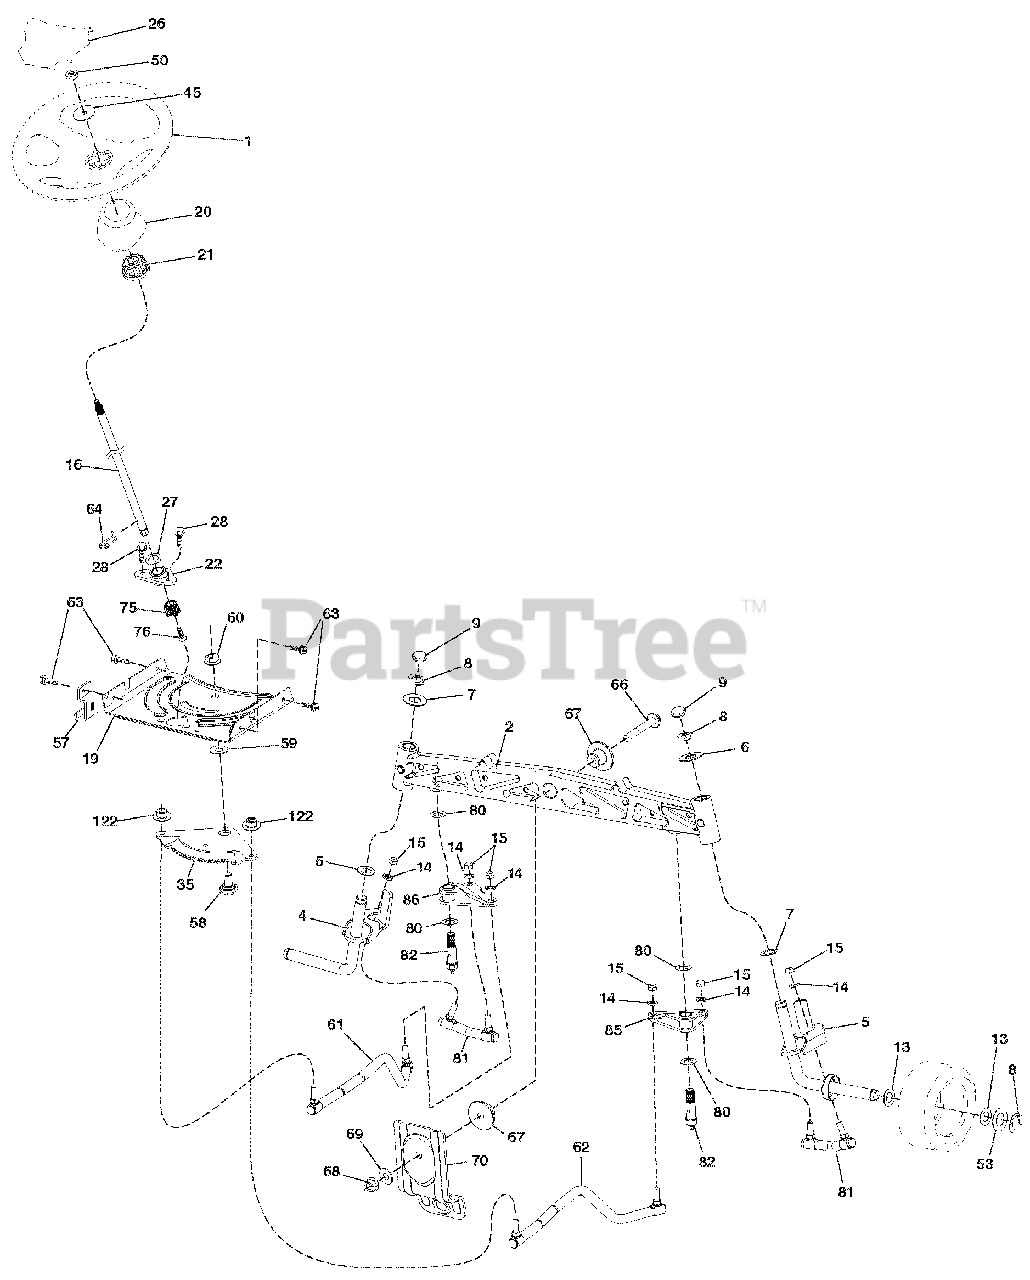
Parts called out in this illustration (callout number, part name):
1	WHEEL STEERING
4	SPINDLE LH
5	SPINDLE RH
6	WAHSER THRUST .75 X 1.230
7	WASHER.25/32 X 1-5/8 X 16GA.
8	RING.KLIP.#T5304-75
9	CAP.SPINDLE.FR.TOP.BLK.
13	WASHER.25/32 X 1 1/4 X 16 GA.
14	Washer, Lock 3/8
15	NUT.CROWNLOCK.3/8-24
16	SHAFT STEER
19	PLATE.STEER.DDL.NLT/NGT
20	BOOT.STEERING
21	ADAPTER.STEER
22	BEARING
26	CAP WHEEL STEERING HRS/SRS BLK
27	WASHER 21/32 X 1 X 1 GA.
28	SCREW.HEXWSH THDR3/8-16X3/4.BL
35	GEAR SECTOR
50	Nut, Hex, Flangelock 3/8-16
53	WASHER.HARDEN..793 X 1.637X060
57	BRACKET.UPSTOP.GT/LT.TEX
58	BOLT.SHOULDER.SECTOR.PIVOT.CFM
59	WASHER.THRUST.SECTOR.STEER.NLT
60	NUT.FLANGE LOCK.5/8-11
61	DRAG LINK LH
62	DRAG LINK RH
63	SCREW.5/16-18X3/4.SMGML.TAP/BL
64	RETAINER.CLIP.SPRING.STEERING
66	BOLT.HEX.FGHD.7/16-14 X 3.SERR
67	BUSHING.PM.FRONT AXLE
68	NUT.LOCK.FLANGE.7/16-14.GR5
69	WASHER.1.5 X .505 X .118
70	BRACKET
75	PINION
81	SUB ASM LINK
82	SUB ASM PIVOT BOLT
85	SUB ASM PIVOT RH
86	SUB ASM PIVOT LH
122	CAP GEAR SECTOR
